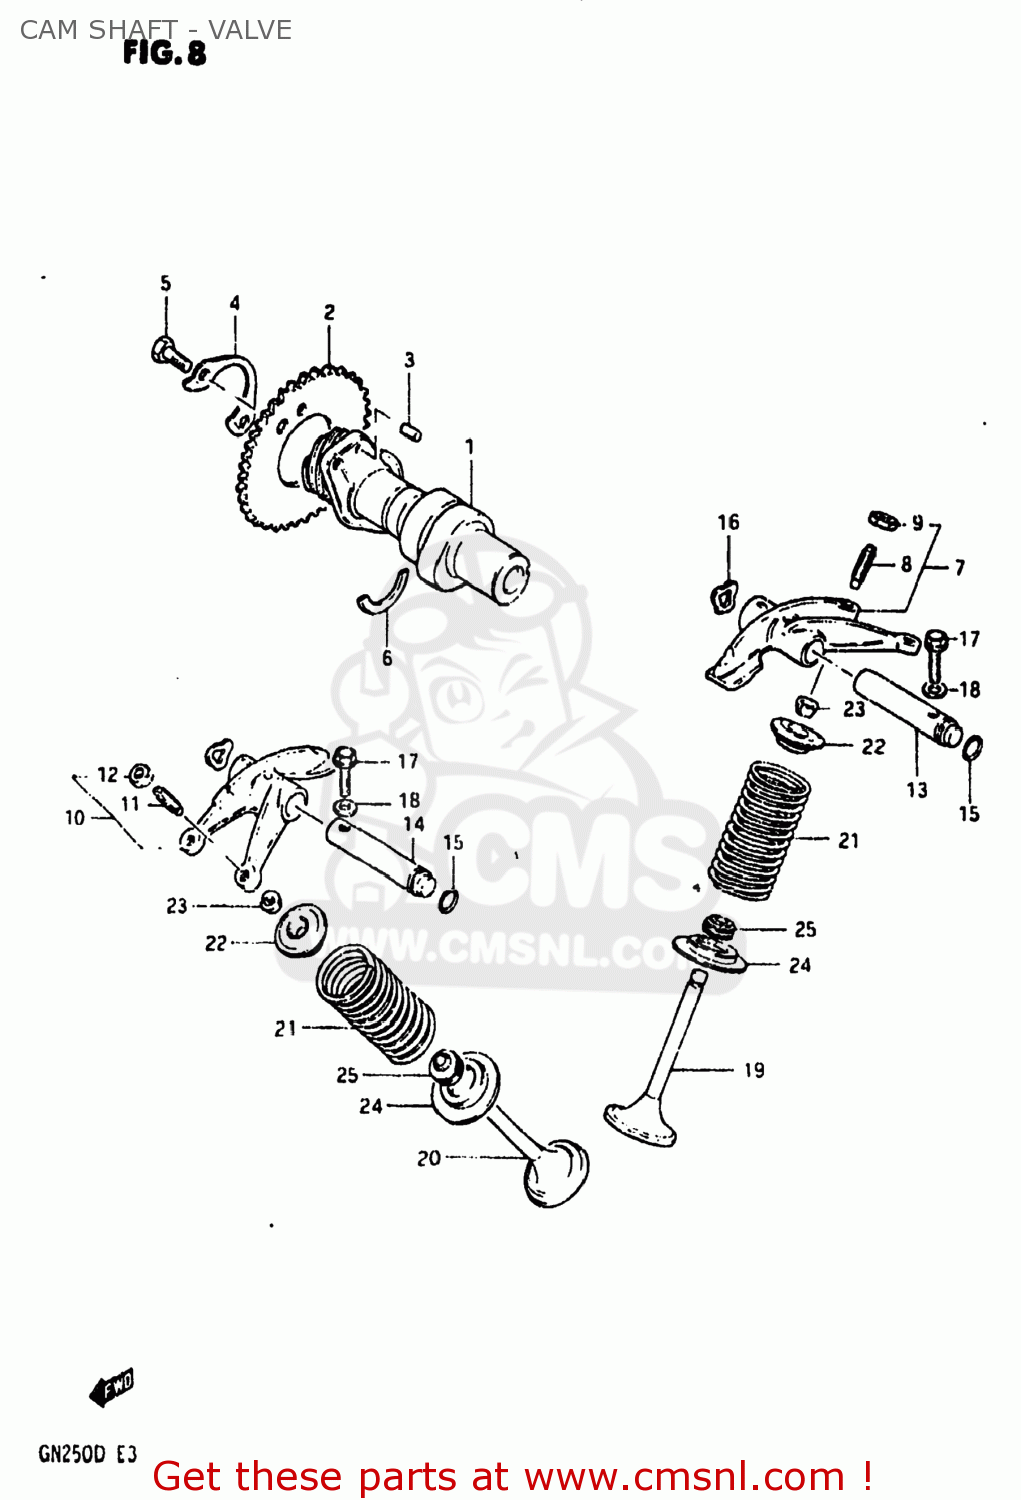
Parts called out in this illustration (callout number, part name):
1	CAMSHAFT
2	SPROCKET,CAMSHAFT(NT:42)
3	PIN
4	WASHER,CAM CHAIN SPROCKET
5	BOLT(6X12.5)
6	C RING
7	ARM,VALVE ROCKER
8	SCREW,TAPPET ADJUSTING
9	NUT,ADJUSTING
10	ARM,VALVE ROCKER,EXHAUST
11	SCREW,TAPPET ADJUSTING
12	NUT,ADJUSTING
13	SHAFT,VLV ROCKER ARM IN(L:91.5
14	SHAFT,VLV ROCKER ARM EXH(L:76)
15	O-RING
16	WASHER
17	BOLT
18	GASKET (NAS)
19	VALVE,INTAKE
20	VALVE,EXHAUST
21	SPRING,VALVE
22	RETAINER,VALVE SPRING
23	COTTER VALVE
24	SEAT,VALVE SPRING
25	OIL SEAL
